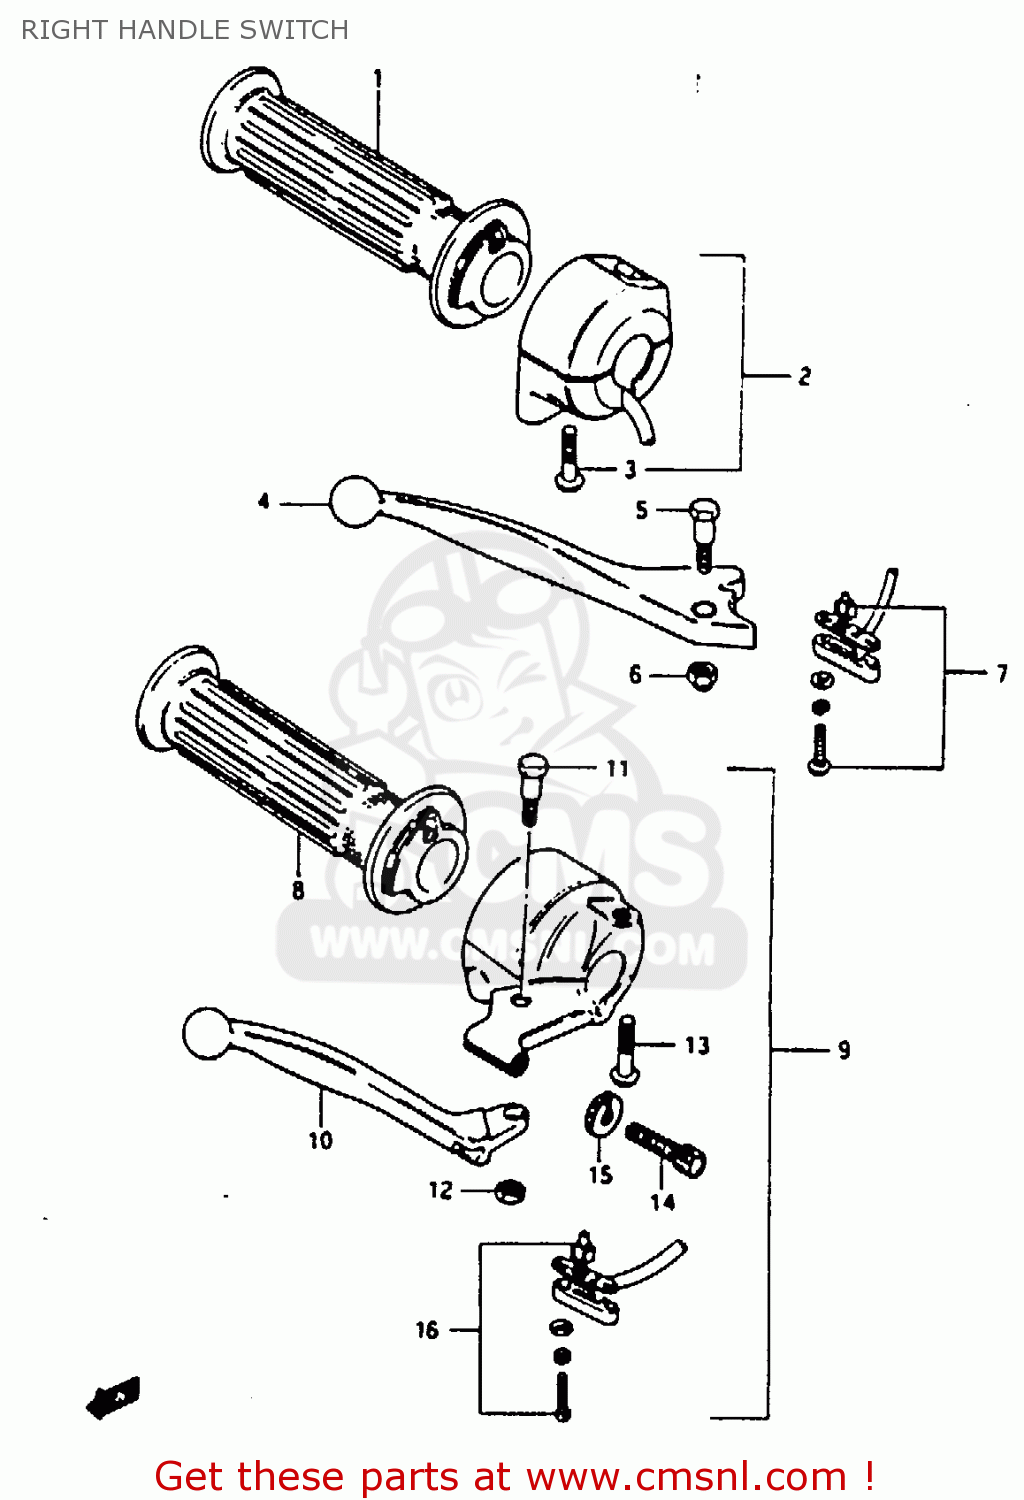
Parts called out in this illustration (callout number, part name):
1	GRIP,THROTTLE
2	CASE ASSEMBLY,THROTTLE
3	SCREW
4	LEVER,BRAKE
5	BOLT
6	NUT 6MM
7	SWITCH ASSY,STOP
8	GRIP,THROTTLE
9	BRAKE LEVER & SWITCH ASSY
10	LEVER,BRAKE
11	BOLT,LEVER PIVOT
12	NUT 6MM
13	SCREW
14	ADJUSTER,CABLE
15	NUT,CABLE ADJUSTER
16	SWITCH ASSY,STOP
